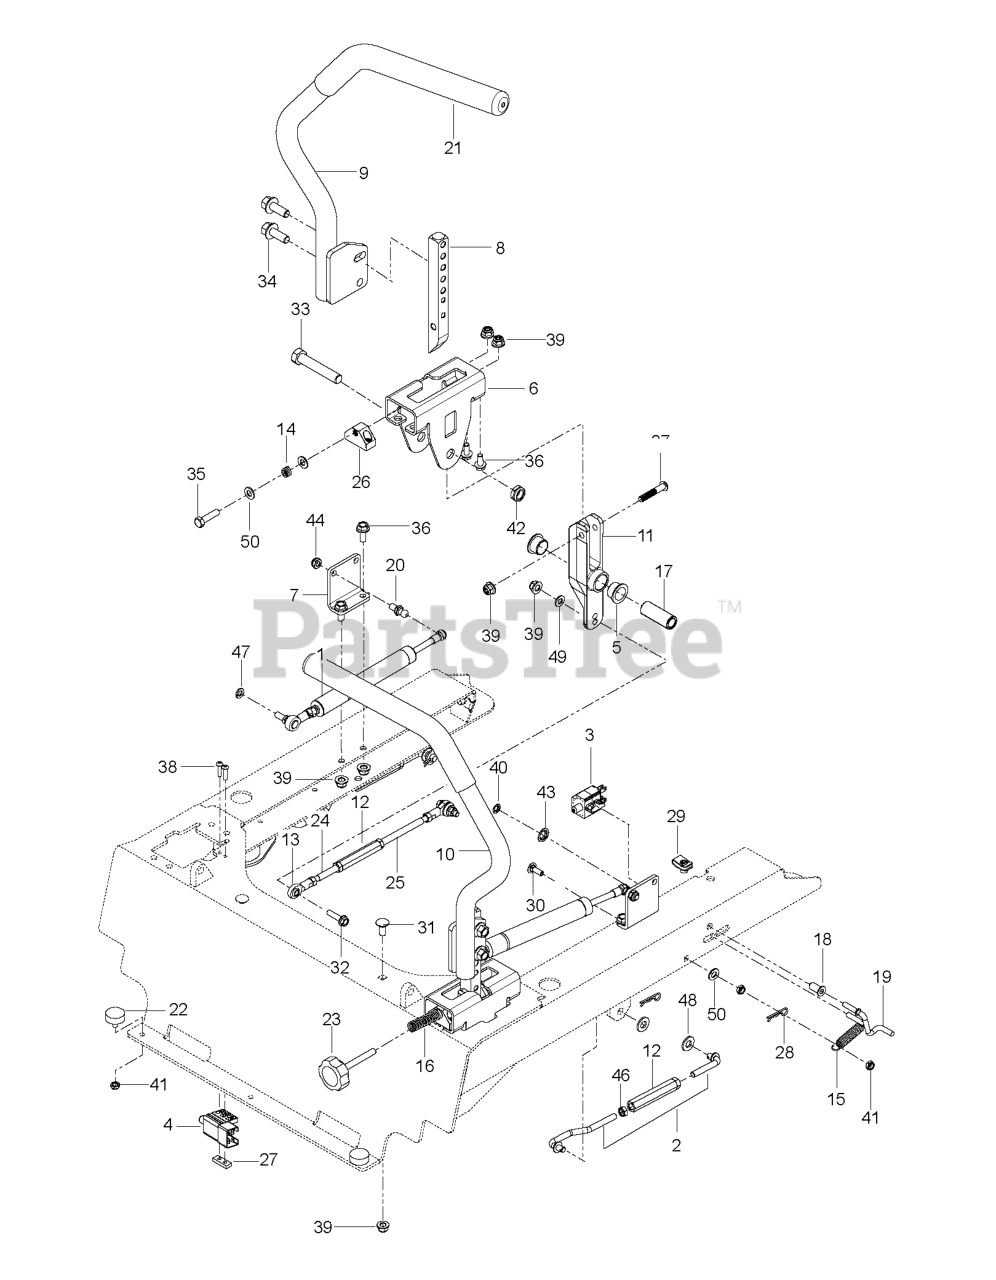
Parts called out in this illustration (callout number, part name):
1	ASSEMBLY, DAMPENER
2	ASSEMBLY, SEAT STRUT
3	SWITCH, BRAKE 3P
4	SWITCH INTERLOCKT
5	BEARING, FLANGE
6	BRACKET.CONTROL.NARROWSLOT.BLK
7	BRACKET.DAMPENER
8	LEVER, MOTION
9	LEVER.WITH GRIP.RT
10	LEVER.WITH GRIP.LT
11	LEVER.CONTROL.SHORT
12	TURNBUCKLE, 3/8
13	BALL JOINT, RIGHT HANDED
15	SPRING, EXTENSION
16	SPRING COMPRESSION 2.0
17	SPACER, PIVOT CONTROL
18	BUSHING, 1/4 FLANGE
19	LINK, SWITCH
20	STUD.BALL.10MM
21	GRIP - DRIVE LEVER 12"
22	BUMPER, 1/4-20 STUD, 1/4
23	KNOB
24	LINKAGE, CONTROL, FT
25	LINKAGE, CONTROL, RR
26	BLOCK TRACKING CONTROL ZTR
27	PLATE NUT ZTR
28	HAIRPIN #2
29	U-CLIP 5/16-18 NUT RETAINER
30	BOLT
31	BOLT 5/16C X 3/4" CARRIAGE
32	HHFS 5/16-18 X 1.25 TPBLT GD 5
33	HCS 1/2-13 X 2-3/4 GD 5 ZD
34	HHFS 3/8-16 X 1 GRD 5 ZD
35	BOLT.5/16-18X1-1/4 FULL.THREAD
36	HHFS 5/16-18 X 3/4
37	SCREW 5/16-18 X 1 3/4 BTN-HD
38	SCR #10-24 X .75 SKT HD BLK
39	5/16-18 NYLOC FLANGE NUT
40	NUT 5/16F
41	JAM NUT 1/4C (2 2 PW01)
42	NUT 1/2-13 HEX JM NYL
43	NUT 3/8 PALNUT RTNG BLK PHOS
44	NUT.71038.31-18.HEX.NYLOCK
46	NUT 3/8-24 JAM
47	WASHER 5/16 LOCK
49	WASHER 5/16 FLAT
50	WASHER
